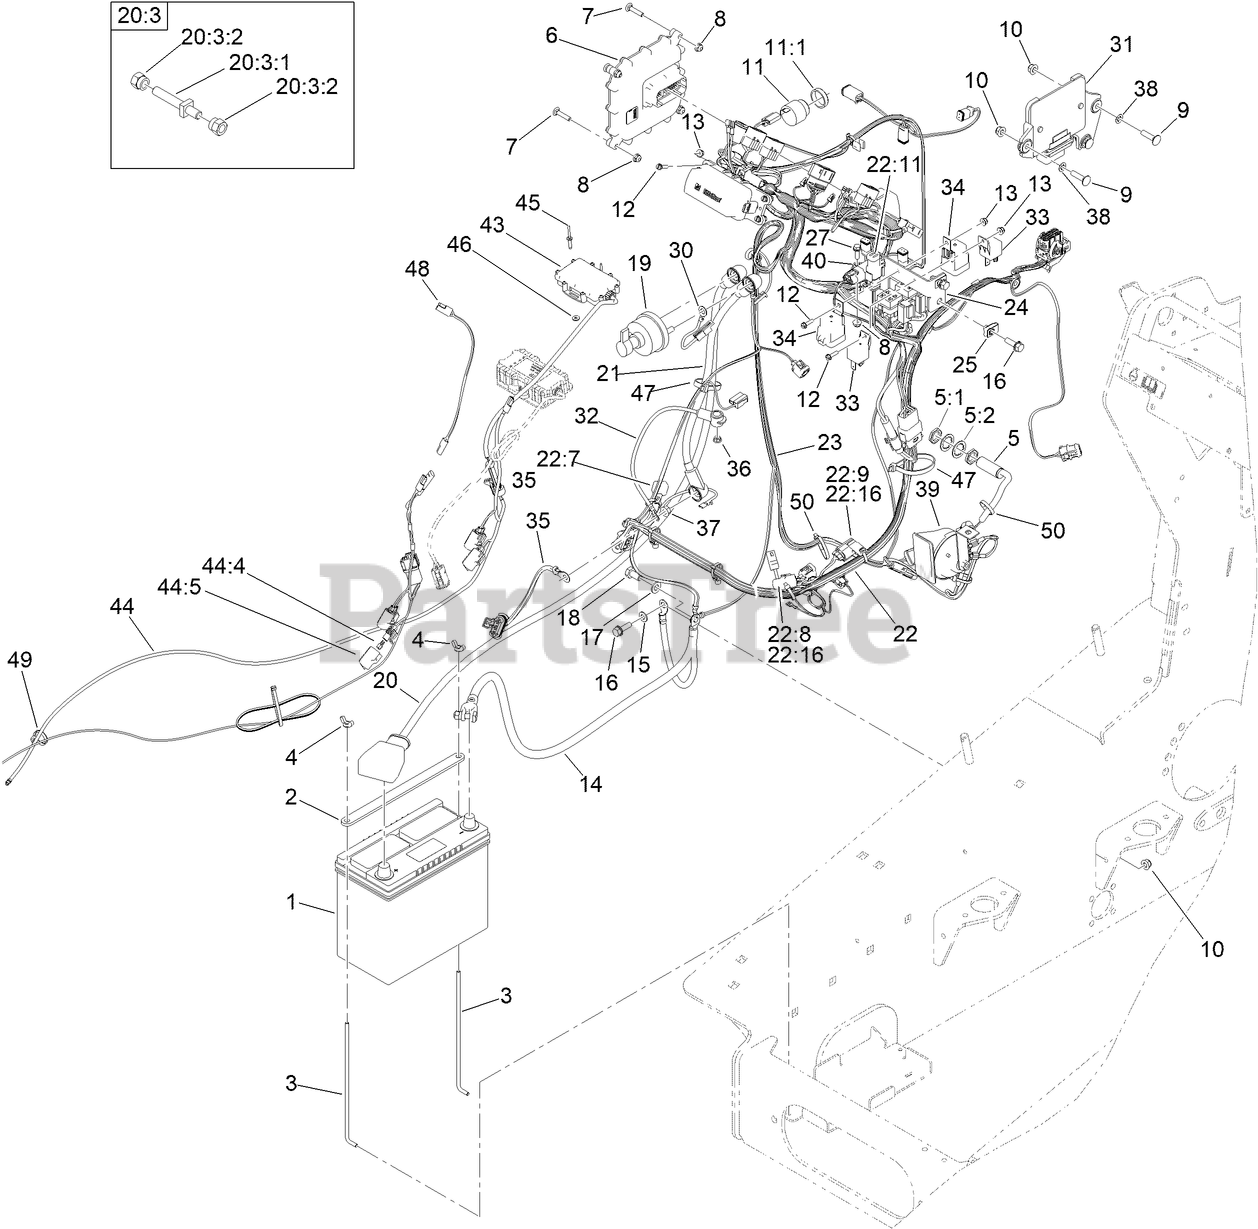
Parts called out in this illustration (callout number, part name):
1	BATTERY-GROUP 51
2	PLATE-HOLD DOWN, BATTERY
3	ROD-HOLD DOWN, BATTERY
4	NUT-WING
5	PROXIMITY SWITCH ASM
5:1	NUT-HEX
5:2	WASHER-LOCK, INTERNAL TOOTH
6	CONTROLLER
7	SCREW-CARR
8	NUT-HF
9	SCREW-CARR
10	NUT-HF, NI
11	AUDIO ALARM ASM
11:1	NUT-PLASTIC, KNURLED
12	SCREW-HWH
13	NUT-HF
14	CABLE-BATTERY, NEGATIVE
15	WASHER-PLAIN
16	SCREW-HHF
17	WASHER-FLAT
18	SCREW-HH
19	SWITCH-DISCONNECT, MASTER
20	CABLE-BATTERY, RD ASM
20:3	BOLT ASM
20:3:1	BOLT-CLAMP, BATTERY
20:3:2	NUT-CLAMP, BATTERY
21	CABLE-BATTERY, RD ASM
22	HARNESS-WIRE, ENGINE
22:8	FUSE-MINI BLADE, 2 AMP
22:9	FUSE-MINI BLADE, 10 AMP
22:11	CONNECTOR (6M)
22:16	COVER-FUSE, SINGLE
23	HARNESS-WIRE, MAIN
24	BRACKET-RELAY
25	NUT-CLIP, U
27	SCREW-HHF
30	HARNESS-WIRE, FUSIBLE LINK
31	CONTROLLER-ENGINE
32	HARNESS-WIRE
33	RELAY
34	RELAY-MINI
35	HARNESS-WIRE, FUSIBLE LINK
36	NUT-HF
37	NUT-HF
38	RING-RETAINING, BOLT
39	Horn And Bracket Assembly (Inc. Ref.# 44 45)
40	SENSOR-ATM
43	GPS ASM
44	HARNESS-WIRE, GPS
44:4	FUSE-MINI BLADE, 5 AMP
44:5	COVER-FUSE, SINGLE
45	RIVET-POP
46	WASHER-PLAIN
47	TIE-CABLE
48	HARNESS-WIRE, SAE J928-2, 12" JUMPER
49	TIE-CABLE
50	TIE-CABLE
